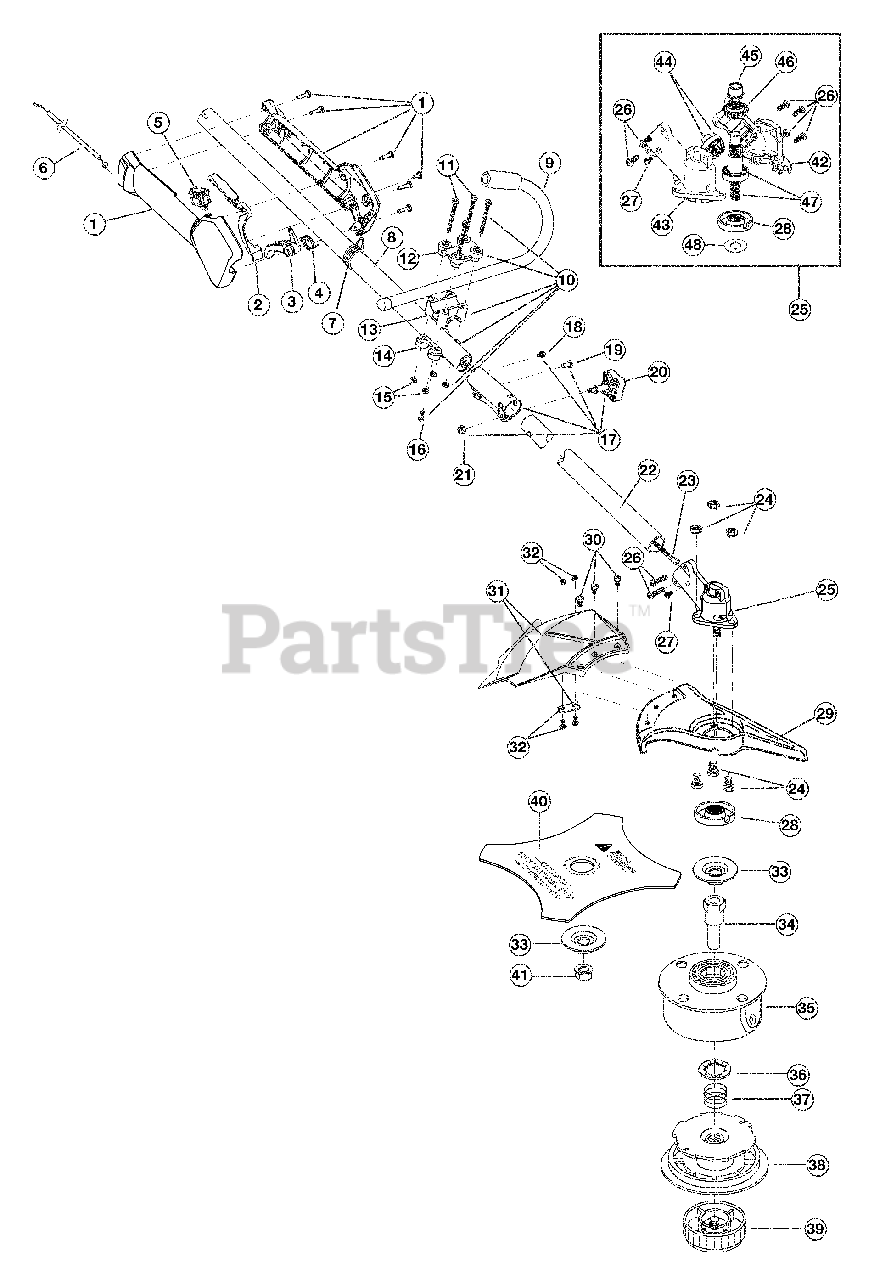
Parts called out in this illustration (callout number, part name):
1	Throttle Housing Assembly
2	Throttle Trigger Lock-Out
3	Throttle Trigger
4	Throttle Trigger Spring
5	Switch Assembly
6	Throttle Cable Assembly
7	Harness Clip
8	Upper Drive Shaft Housing Assembly
9	J-Handle Assembly
10	Handle Bracket Assembly
12	Upper Handle Clamp
13	Middle Handle Clamp
14	Lower Handle Clamp
16	Anti-Rotation Screw
17	Split Boom Coupler
20	Adjustment Knob
21	Knob Retaining Nut
22	Lower Drive Shaft Housing Assembly
23	Lower Flexible Drive Shaft
24	Shield Mount Screw Assembly
25	2 piece Gearbox Assembly
26	Gearbox Mounting Hardware
27	Anti-Rotation Screws
28	Blade Driver
29	Blade Shield/Shield Mount
30	Shield Mounting Screw
31	Shield Assembly
32	Blade Assembly
33	Retaining Washer
34	Spool Shaft
35	Outer Spool Assembly
36	Retainer
37	Spring
38	Inner Reel
39	Bump Head Knob Assembly
40	4-Tooth Blade
41	Nut
42	Left Housing
43	Right Housing
44	Pinion Gear Assembly
45	Output Shaft Bushing
46	Output Shaft Gear
47	Output Shaft Assembly
48	Palnut
